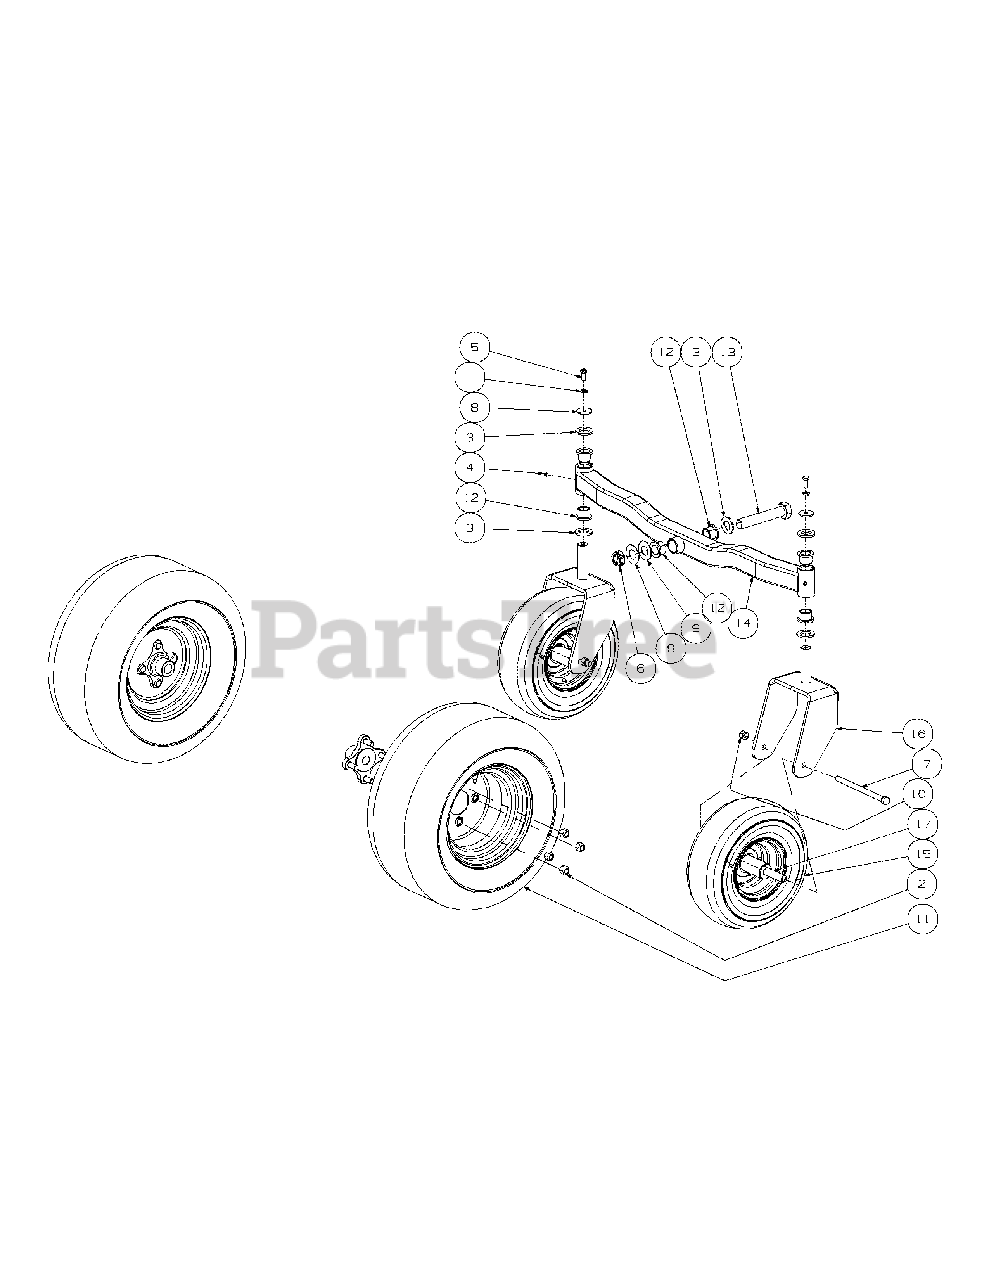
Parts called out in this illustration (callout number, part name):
1	Lock Washer, 3/8 Zinc
2	Lug Nut, 1/2-20
3	Washer Special
4	Grease Fitting, 1/4-28 x 3/16
5	Hex Cap Screw, 3/8-16 x .88
6	Nut Jam, 1.0-14, Nylon Insert
7	Hex Cap Screw, 1/2-20 x 7.50
8	Flat Washer, .390 x 1.5 x .134
9	Flat Washer, 1.00 ID x 2.25 OD x ,075
10	Lock Nut, Nylon Insert, 1/2-20
11	Wheel Assembly, 20 x 10.00 x 10
12	Flange Bearing, 1.001 x 1.25
13	Hex Cap Screw, 1-14 x 5.5
14	Front Axle Assembly
15	Wheel Assembly 13 x 5.00 - 6, Beige
16	Castor Wheel Mounting Bracket
17	Wheel Spacer
